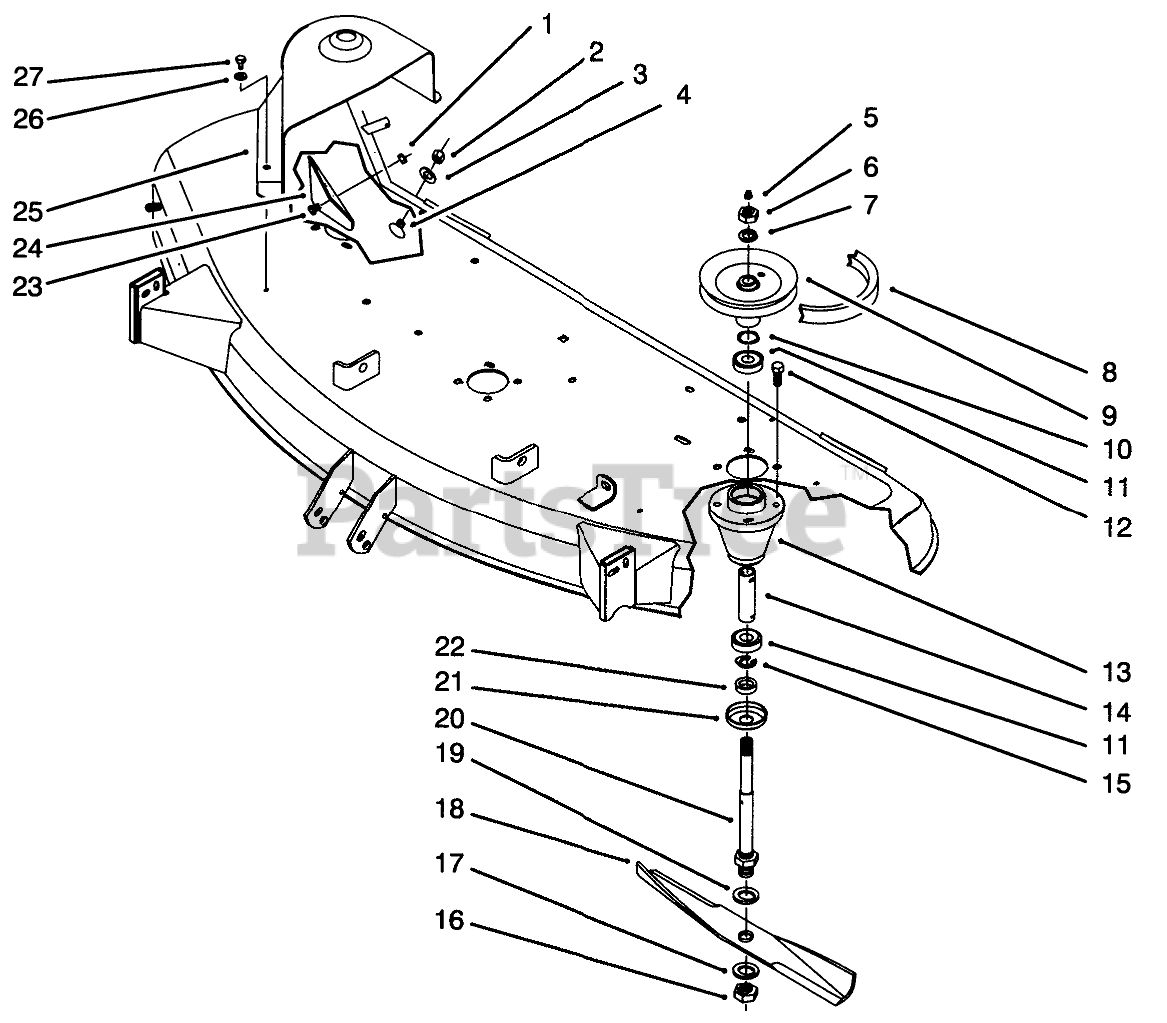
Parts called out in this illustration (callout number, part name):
1	NUT-LOCK, NI
2	NUT-LOCK, NI
3	WASHER-FLAT
4	SCREW-CARR
5	FITTING-GREASE
6	NUT-JAM
7	WASHER-LOCK
8	Belt-V
9	Pulley-Spindle
10	O RING
11	BEARING-BALL
12	SCREW-HH
13	HOUSING-SPINDLE
15	RING-RETAINING
16	NUT-JAM
17	WASHER-FLAT
18	BLADE KIT (3 PACK)
19	Washer
20	SHAFT-SPINDLE
21	CUP-SPINDLE
22	SPACER-BLADE
23	SCREW-HH
24	Guard-Chute
25	COVER-BELT, RH
26	WASHER-FLAT
27	Bolt
